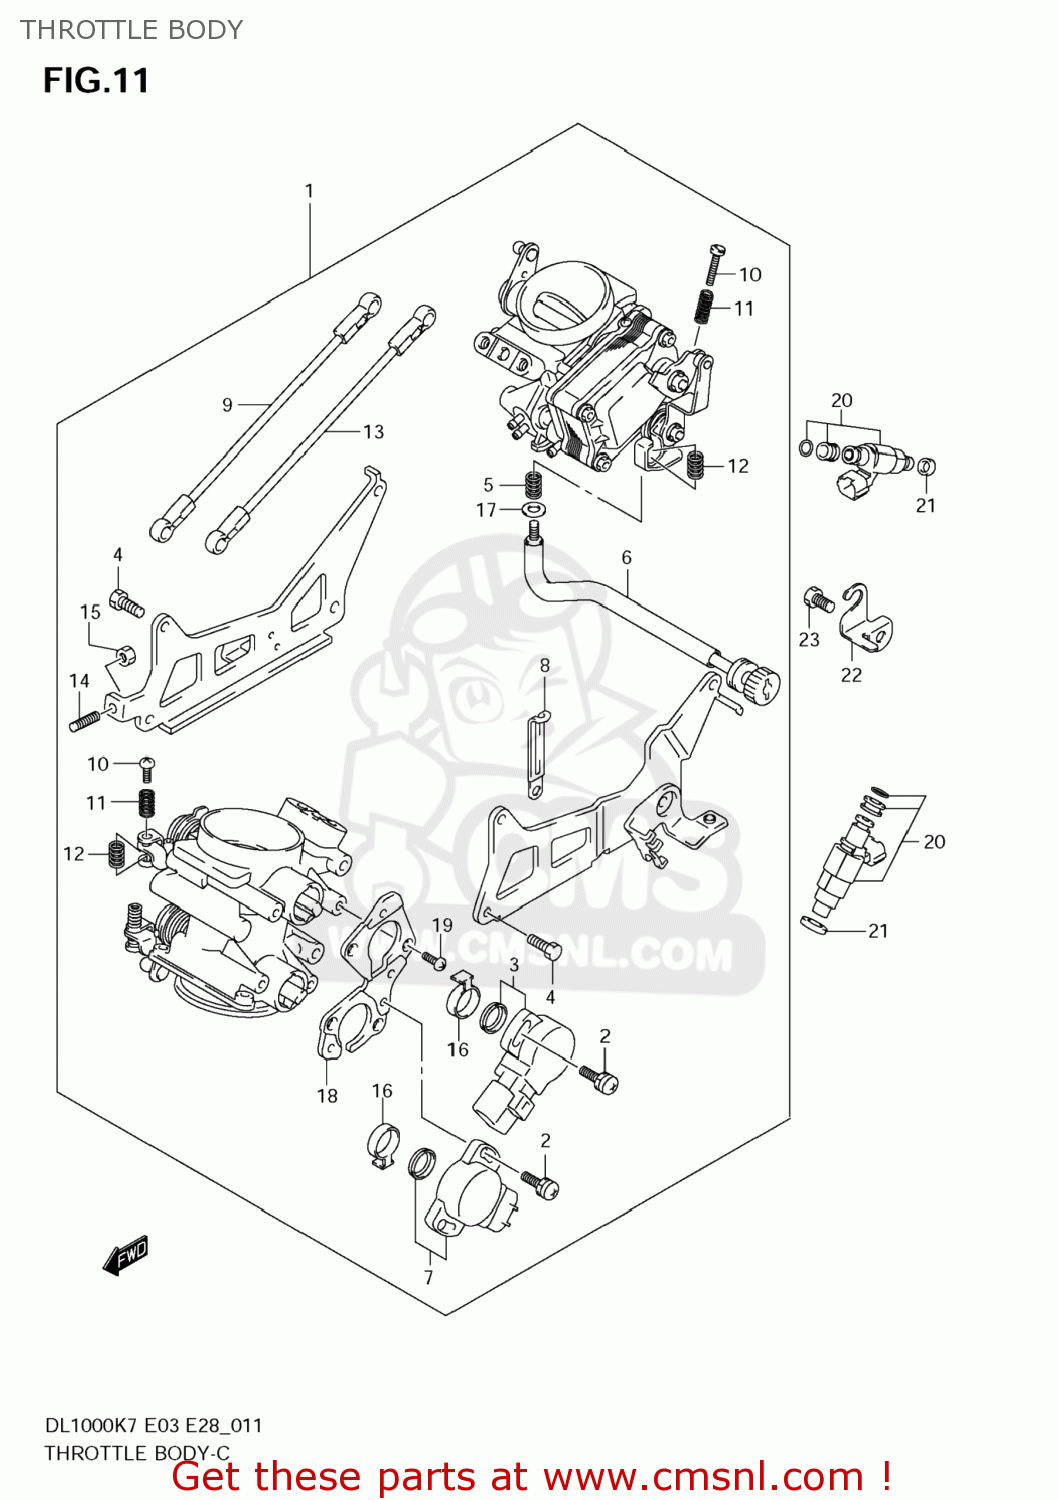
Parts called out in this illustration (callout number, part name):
1	BODY ASSY,THROTTLE
2	SCREW
3	SENSOR ASSY
4	BOLT
5	SPRING
6	SCREW ASSY,ADJUST
7	SENSOR ASSY,THROTTLE
8	CLAMP(L:45)
9	ROD ASSY
10	SCREW
11	SPRING
12	SPRING
13	ROD ASSY
14	SCREW,ADJUST
15	NUT
16	RING
17	WASHER
18	PLATE
19	SCREW
20	INJECTOR ASSY
21	CUSHION,FUEL INJECTOR
22	PLATE,IDLE ADJUST
23	BOLT
